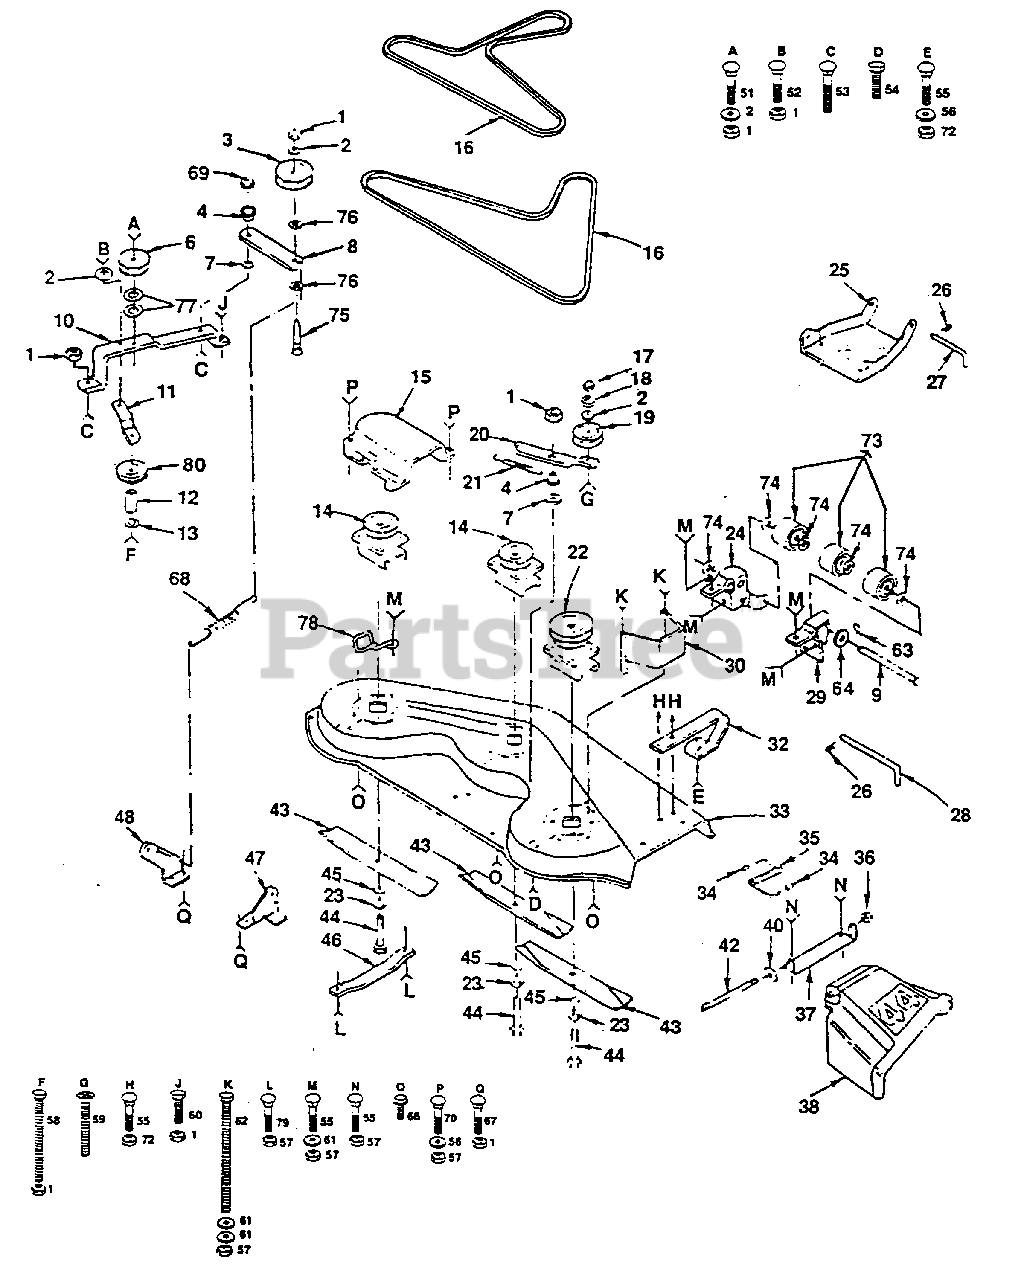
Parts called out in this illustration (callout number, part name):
1	Locknut 3/8 x 16
2	Washer 13/32 x 1 x 14 Ga. (AYP part number)
3	Pulley, Idler (AYP part number)
4	Spacer (AYP part number)
6	Pulley, Idler (AYP part number)
7	Washer, Wear (AYP part number)
8	Arm, Idler (AYP part number)
9	Pin, Pivot (AYP part number)
10	Bar, Support, Idler (AYP part number)
11	Brace, Idler, Deck (AYP part number)
12	Spacer (AYP part number)
13	Washer 13/32 x 13/16 x 16 Ga. (AYP part number)
14	Mandrel, Secondary (AYP part number)
15	Guard (AYP part number)
16	V-Belt (AYP part number)
17	Nut, Hex 3/8 x 16 (AYP part number)
18	Washer, Lock 3/8 (AYP part number)
19	Idler, Flat (AYP part number)
20	Arm, Idler, Deck (AYP part number)
21	Spring, Extension (AYP part number)
22	Mandrel, Primary (AYP part number)
23	Washer, Lock, Hvy. Helical (AYP part number)
24	Bracket, Lift, LH (AYP part number)
25	Link, Parallel (AYP part number)
26	Retainer, Spring (AYP part number)
27	Pin, Front, Hinge (AYP part number)
28	Pin, Rear, Hinge (AYP part number)
29	Bracket, Lift, RH (AYP part number)
30	Guard, Belt, RH (AYP part number)
32	Runner, RH (AYP part number)
33	Housing, Mower (AYP part number)
34	Cap, Sleeve (AYP part number)
35	Spring (AYP part number)
36	Nut, Push (AYP part number)
37	Bracket, Deflector (AYP part number)
38	Guard, Discharge (AYP part number)
40	Washer 11/32 x 5/8 x 16 Ga. (AYP part number)
42	Rod, Hinge (AYP part number)
43	Blade (AYP part number)
44	Bolt, Hex 3/8-24 x 1 1/2 Gr.5 (AYP part number)
45	Washer 13/32 x 1 1/4 x 12 Ga. (AYP part number)
46	Runner, LH (AYP part number)
47	Bracket, Suspension, Rear, RH (AYP part number)
48	Bracket, Suspension, Rear, LH (AYP part number)
51	Bolt, Carriage 3/8-16 x 1-3/4 (AYP part number)
52	Bolt, Carriage 3/8-16 x 1 (AYP part number)
53	Bolt, Carriage 3/8-16 x 1 1/2 (AYP part number)
54	Bolt, Hex 3/8-16 x 1-1/4 (AYP part number)
55	Bolt, Carriage 5/16-18 x 3/4
56	Washer 11/32 x 11/16 x 16 Ga. (AYP part number)
57	Locknut 5/16-18
58	Bolt, Hex 3/8-16 x 3 (AYP part number)
59	Screw, Flat Head 3/8-16 x 2 (AYP part number)
60	Bolt, Fin. Hex 3/8-16 X 1 (AYP part number)
61	Washer 11/32 x 3/4 x 16 Ga. (AYP part number)
62	Bolt, Hex 5/16-18 x 5 (AYP part number)
63	Pin, Cotter (AYP part number)
64	Washer, 15/32 X 1X 16 Ga. (AYP part number)
66	Screw, Hex Washer Thread Rolling 3/8-16x3/4 (AYP part number)
67	Bolt, Carriage 3/8-16 x 3/4 (AYP part number)
68	Spring, Extension (AYP part number)
69	Nut.Centerlock 3/8-16 (AYP part number)
70	Bolt, Carriage 5/16-18 x 3/4 (AYP part number)
72	Locknut 5/16-18 (AYP part number)
73	Roller, Nose (AYP part number)
74	Washer 15/32 x 1 x 10 Ga. (AYP part number)
75	Bolt, Carriage 3/8-16 x 2-1/2 (AYP part number)
76	Washer 13/32 x 3/4 x 10 Ga. (AYP part number)
77	Washer 13/32 x 7/8 x 10 Ga. (AYP part number)
78	Keeper, L.H. Mandrel (AYP part number)
79	Bolt, Carriage 5/16-18 x 5/8 (AYP part number)
80	Idler, Pulley (AYP part number)
